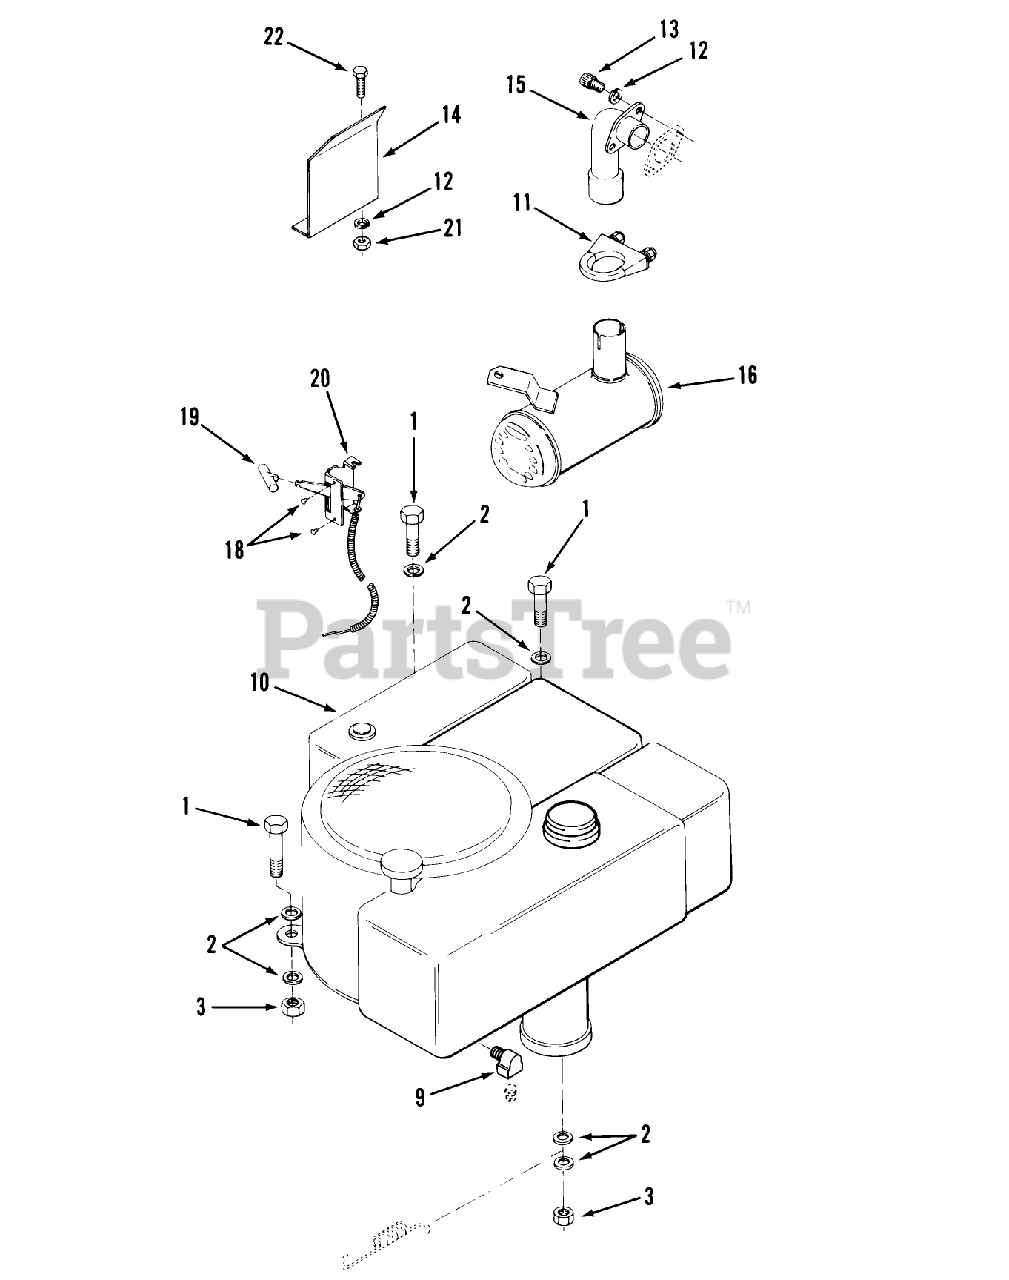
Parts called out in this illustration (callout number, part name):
2	WASHER 5/16 SAE
2	WASHER
10	Engine 8 H.P.-BS Model 191707 Type 5821-01 A-81 Only
10	Engine 11 H.P.-BS Model 252707 Type 0648-01 A-111 Only
13	SHCS 5/16-18X.625
18	RIVET
